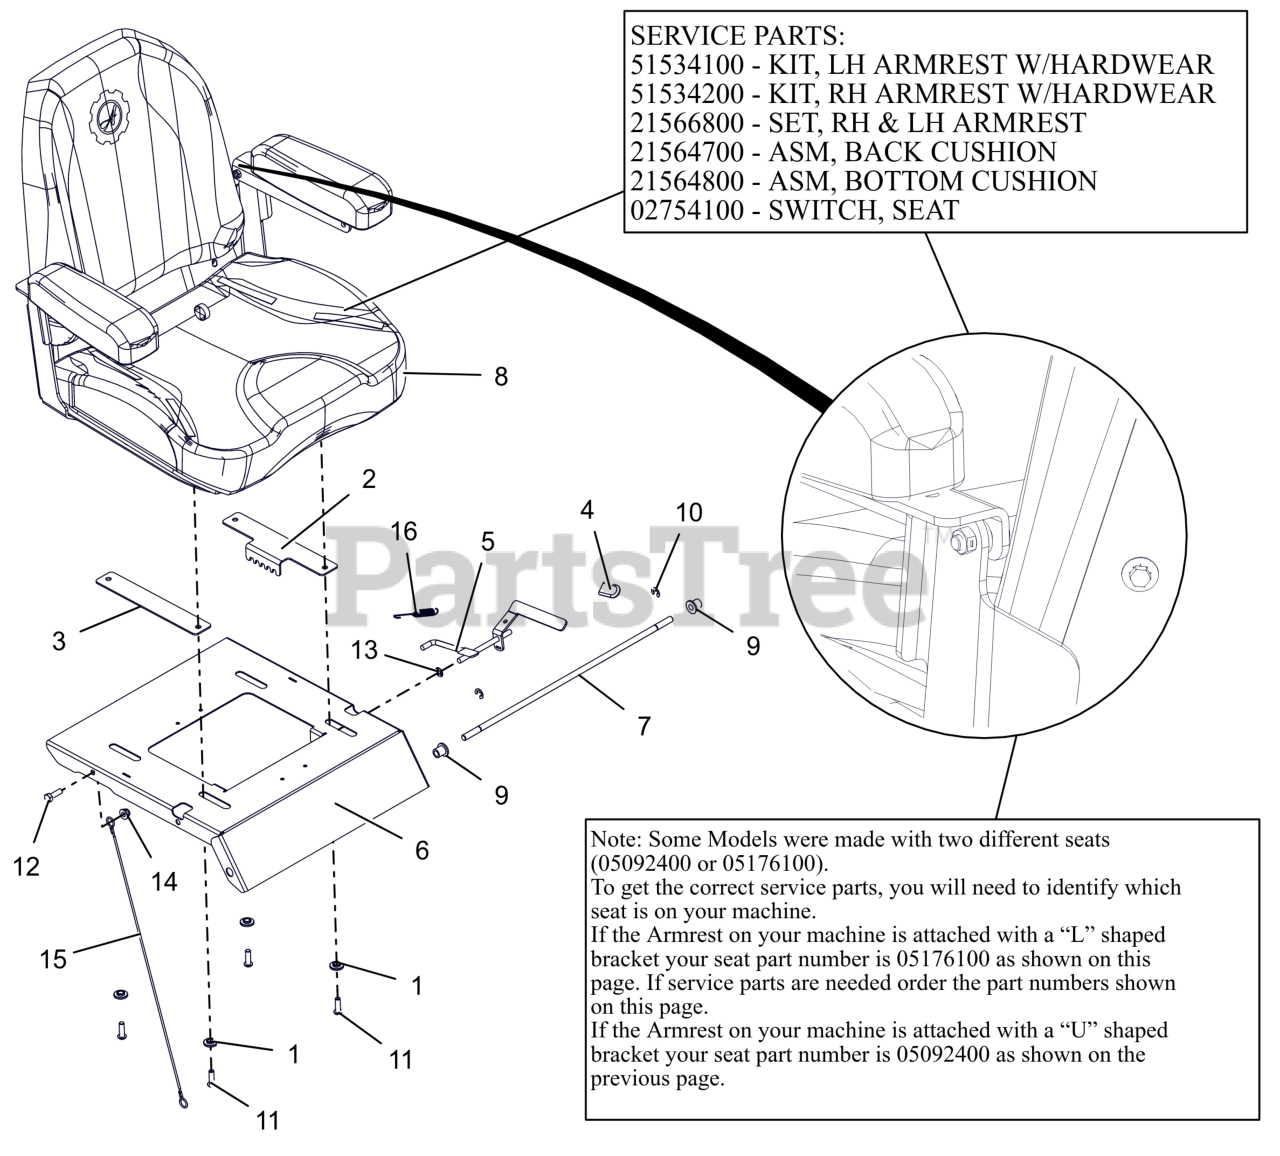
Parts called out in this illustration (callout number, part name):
1	BSHG, FLG .312X.499X.23X.88
2	PLATE, ADJUSTABLE SEAT TRACK
3	PLATE, ADJUSTABLE SEAT SLIDE
4	GRIP, SEAT LEVER, GREY
5	WLDMT, ADJUSTABLE SEAT LATCH
6	PLATE, SEAT
7	ROD, SEAT PIVOT
8	SEAT, IKON XL
8	KIT, ARMREST LH W/HDWR
8	KIT, ARMREST RH W/HDWR
8	SET, LH & RH ARMREST
8	ASM, BACK CUSHION-ARIENS X
8	ASM, BOTTOM CUSHION-ARIENS X
8	SWITCH- SNAP MTG N.O.
9	BSHG-FLG .38X.580X.667X.750
10	RG-RTNG-EXT .375X.035 TYP E
11	BLT,SHCS-BTN .31-18X1.00 ZCC
12	BLT,HEX .31-18X1.00 G5 ZCC
13	NUT-PUSH .312
14	NUT,LK-NYL-FLG .31-18 G5ZC120
15	LANYARD, SEAT CABLE .093X19.5
16	SG-TENS .043X.44X3.31 WLD 5.8
